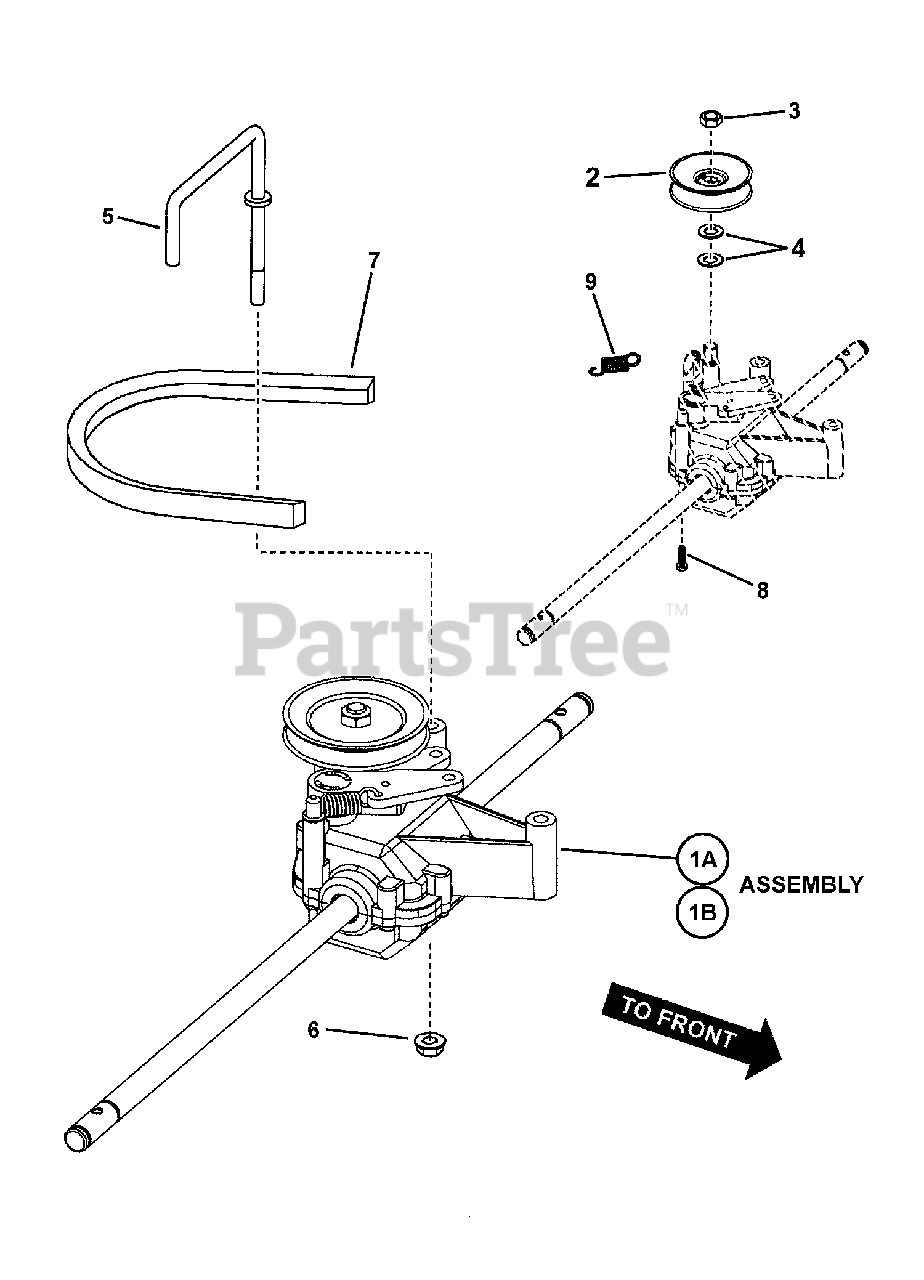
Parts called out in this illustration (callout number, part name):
1A	TRANSMISSION, LC Walk, Single Speed
1B	TRANSMISSION, LC Walk, Variable Speed
2	PULLEY, Transmission, Single Speed Low Cost Walk
2	PULLEY, Transmission, Variable Speed Low Cost Walk
3	NUT, 3/8-16 Hex Center Lock Jam
4	WASHER, .390 I.D.
5	BELT GUIDE, Variable Speed
6	NUT, 1/4-20 Hex Top Lock Flange, GR B
7	BELT, 3L, Traction Drive
8	SCREW, 7mm x 1 x .550 AB Point
9	SPRING, Clutch Return
